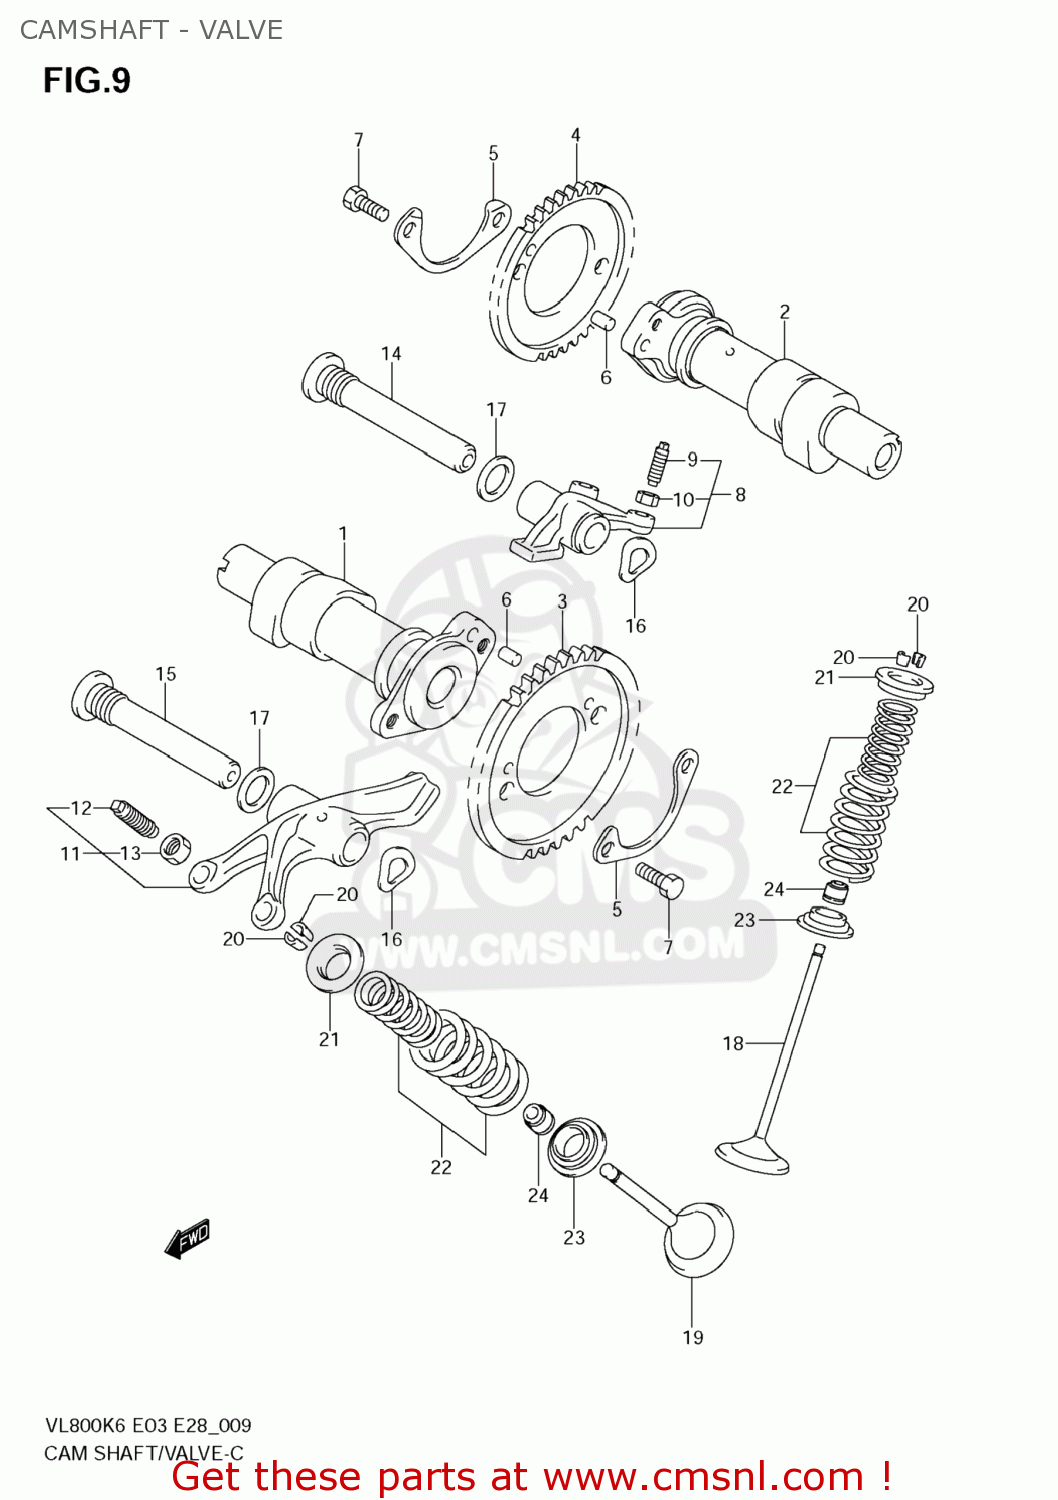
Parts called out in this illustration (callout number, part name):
1	CAMSHAFT,FR
2	CAMSHAFT,RR
3	SPROCKET,CAMSHAFT
4	SPROCKET,CAMSHAFT(NT:42)
5	WASHER,SPROCKET
6	PIN
7	BOLT(6X12.5)
8	ARM COMP,INTAKE VALVE ROCKER
9	SCREW,TAPPET ADJUSTING
10	NUT,ADJUSTING SCREW
11	ARM,EXHAUST VALVE ROCKER FR
12	SCREW,TAPPET ADJUSTING
13	NUT,ADJUSTING SCREW
14	SHAFT,VALVE ROCKER ARM
15	SHAFT,VALVE ROCKER ARM
16	WASHER
17	GASKET(13.8X18.8X4.8) (NAS)
18	VALVE,INTAKE
19	VALVE,EXHAUST
20	COTTER,VALVE
21	RETAINER,VALVE SPRING
22	SPRING SET,VALVE
23	SEAT,VALVE SPRING
24	SEAL,OIL(5.5X11X8.2)
